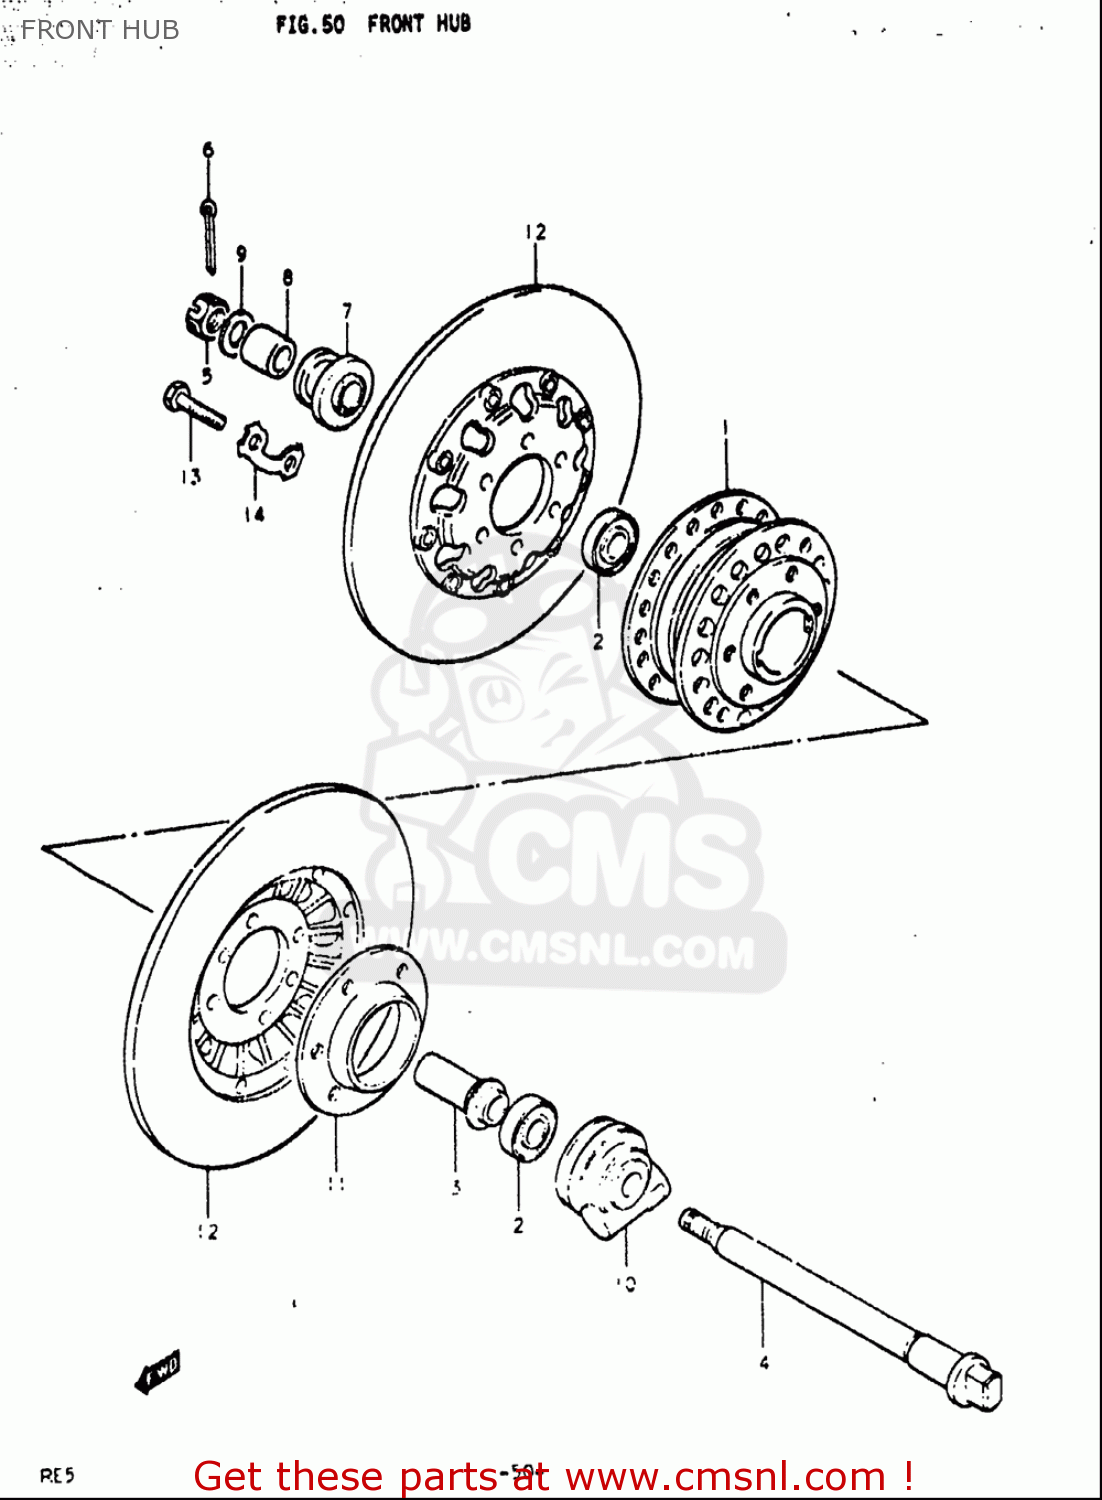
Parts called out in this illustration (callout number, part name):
1	HUB,FRONT WHEEL
3	SPACER,FR HUB BEARING
4	AXLE,FRONT
5	NUT 12MM
6	PIN
7	SPACER,FR AXLE,R
8	SPACER(15X22X30)
9	WASHER
10	BOX ASSY,SPEEDOMETER GEAR
13	BOLT(8X30)
14	WASHER
